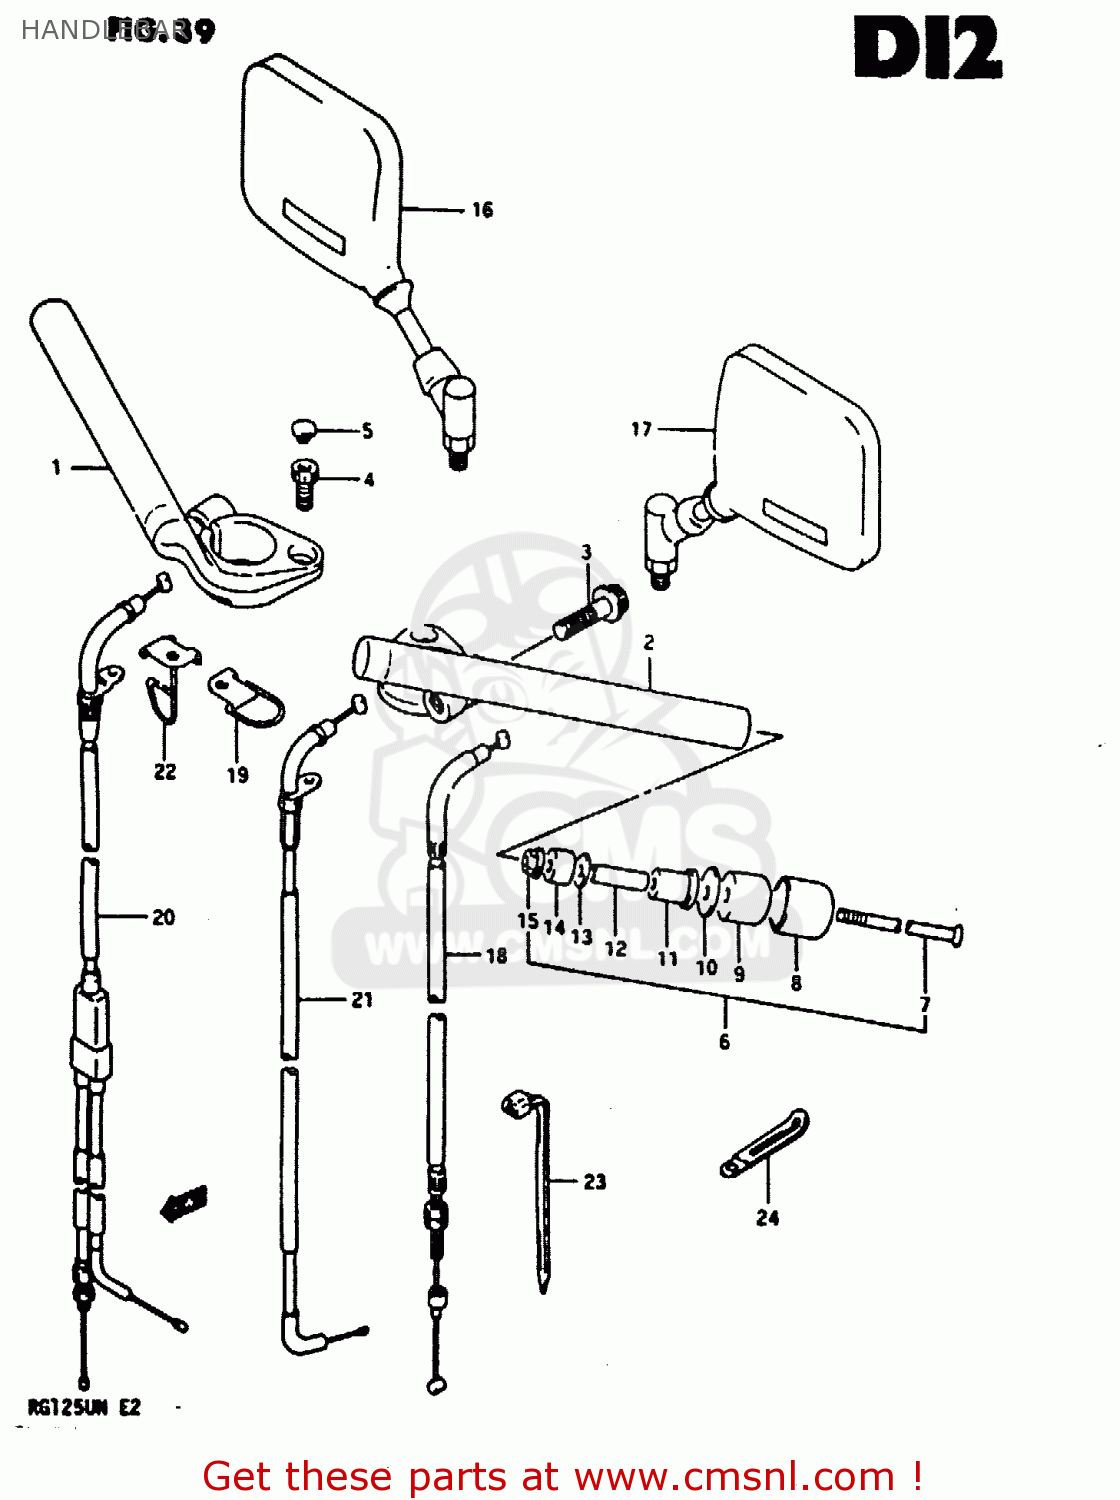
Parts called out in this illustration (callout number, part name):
1	HANDLEBAR, RH
2	HANDLEBAR,L
3	BOLT
4	BOLT
5	CAP(OD:11)
6	BALANCER SET, HANDLEBAR
7	SCREW(6X127)
8	CAP,HANDLEBAR BALANCER
9	BALANCER,HANDLE
10	SPACER,BALANCER
11	EXPANDER,HANDLE BALANCER
12	SPACER,EXPANDER
13	WASHER
14	EXPANDER,HANDLE
15	NUT
16	MIRROR ASSY, REAR VIEW RH
17	MIRROR ASSY, REAR VIEW LH
18	CABLE,CLUTCH
19	GUIDE, CLUTCH CABLE
20	CABLE ASSY,THROTTLE
21	CABLE, STARTER
22	GUIDE,STARTER CABLE
23	CLAMP(L:125)
24	CLAMP
